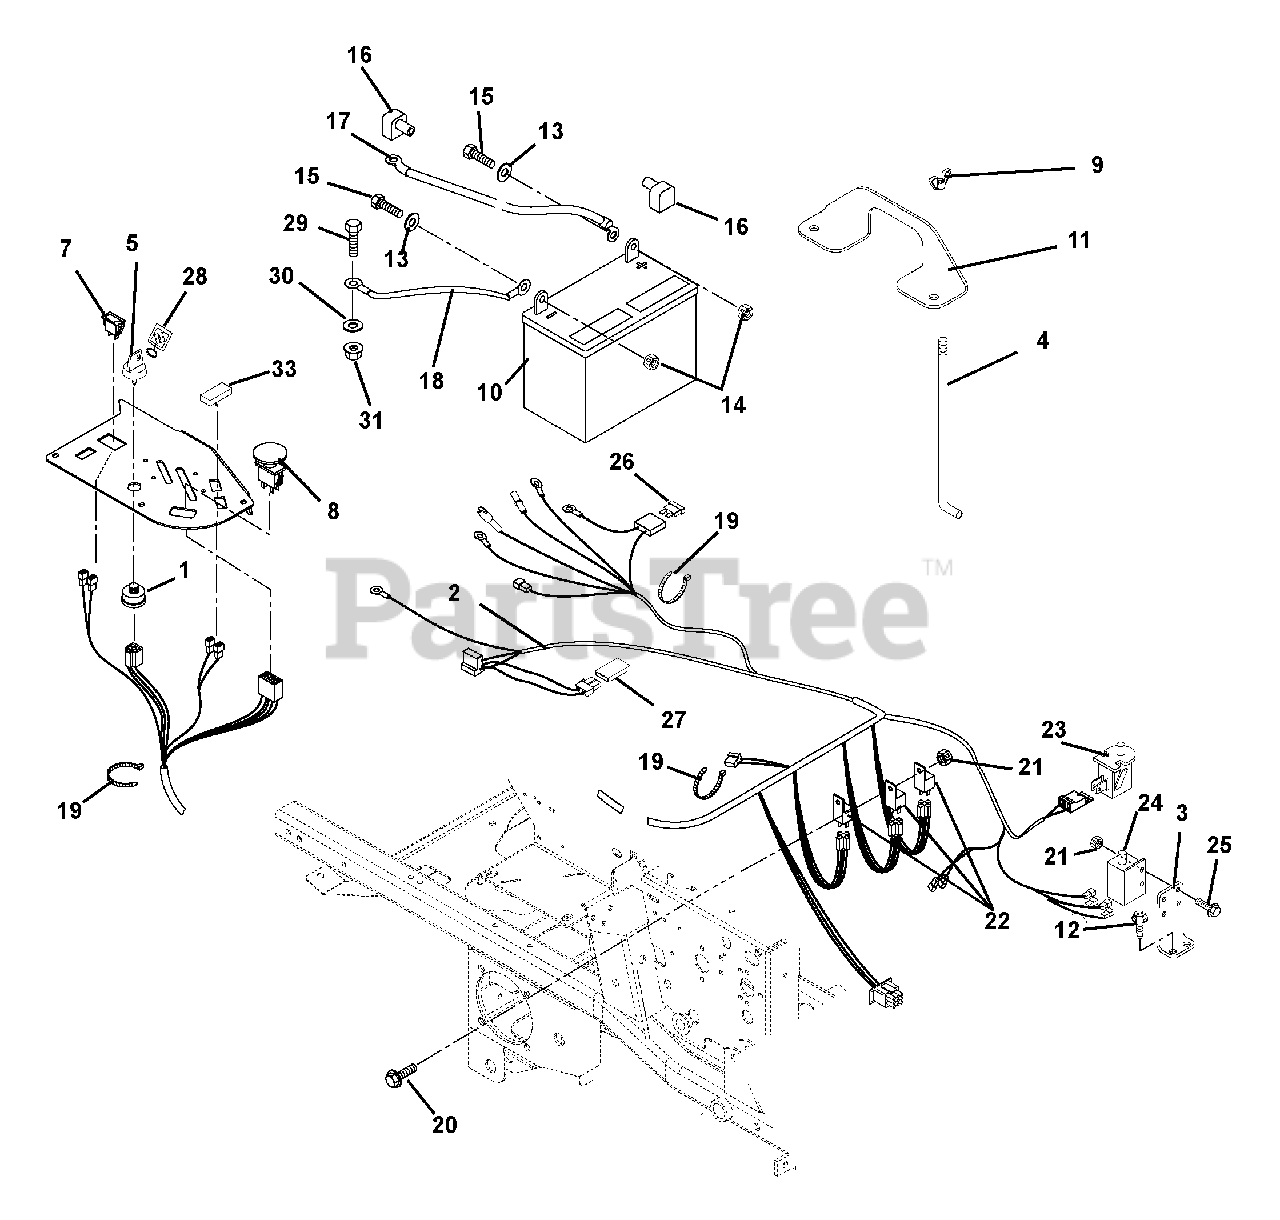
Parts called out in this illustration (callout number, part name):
1	Switch, Ignition
2	Harness, MZ Vertical A/C (992111, 115, 127, 128, 129, 131, 132, 133, 145)
2	Harness, L/C Gas (992113, 117, 124, 130, 134, 135, 139)
3	Mount, Safety Switch
4	Rod, Battery Holddown .25 x 6.62
5	Key, with Shield
6	Ignition Key Set
7	Hour Meter
8	Switch, PTO Clutch
9	Nut-Locking Wing .25-20
10	Battery, 12V
11	Hold Down, Battery
12	Screw-Tapping .25-20 x .50 Hex Washer Head
13	Washer-Flat-Steel .281 x .620 x .065
14	Nut-Locking-Top-Flange .25-20
15	Bolt-Hex .25-20 x .75 Grade 5
16	Battery Terminal Boot, Red
17	Starter Cable 13 in.
18	Ground Cable
19	Cable Tie
20	Screw-Machine 10-24 x .50 Hex Washer Head
21	Nut-Locking-Nylon 10-24 With Insert
22	Relay
23	Switch- Snap Mounting
24	Switch- Double Pole N.O./N.O.
25	Screw-Machine 10-24 x .75 Hex Washer Head
26	Fuse, 30 Amp
27	Diode, Connector Shell
28	Key Chain
29	Bolt-Hex .31-18 x .75 Grade 5
30	Washer-Flat-Steel .344 x .688 x .065
31	Nut-Locking-Top-Flange .31-18
32	Switch, Blank
33	Light, Indicator
